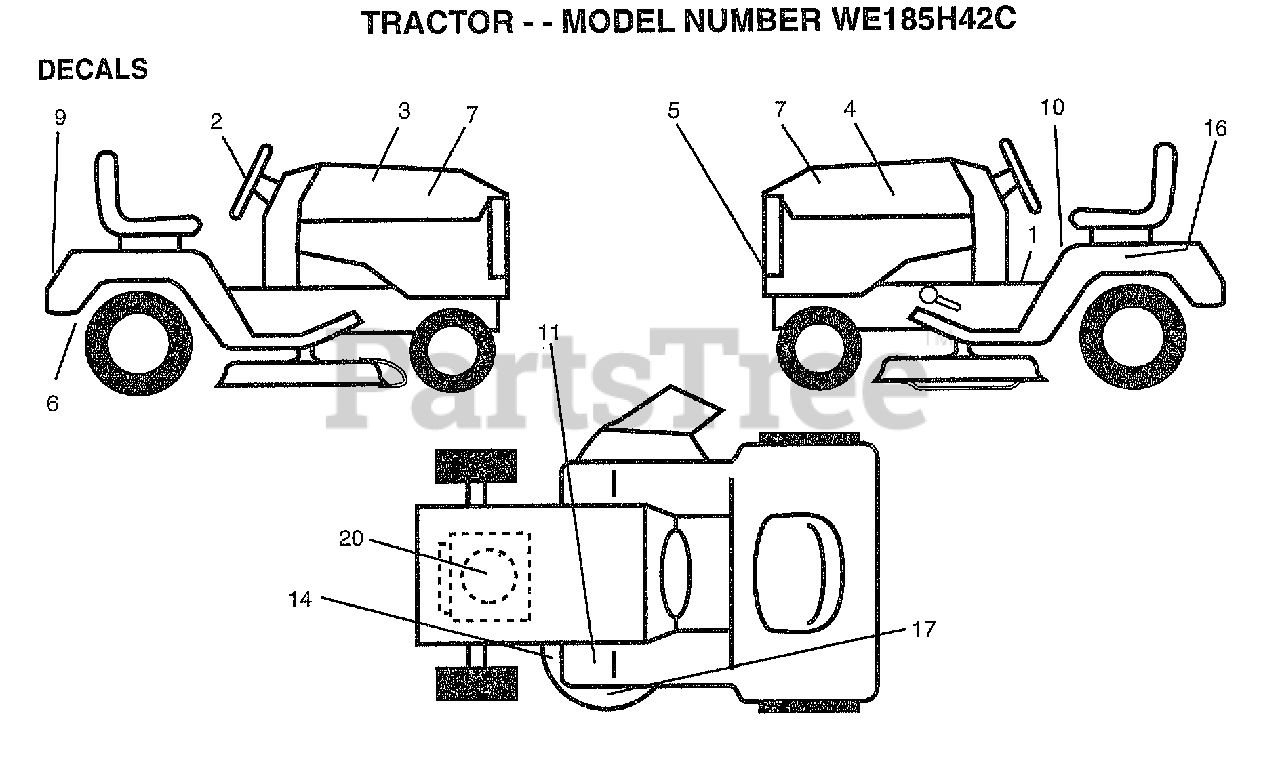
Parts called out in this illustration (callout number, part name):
1	"DECAL INST,SADDLE"
2	"DECAL INS,STRG WH"
3	"DECAL HOOD,RH"
4	DECAL HOOD LH
5	"DECAL GRILLE,LENS"
6	DECAL DRAWBAR LH
7	DECAL PANEL SIDE
9	DECAL-FENDER
10	"DECAL DANGER,FEND"
14	"DECAL-SCHEM,BELT"
16	DECAL.BATRY.3-3908
20	DECAL, HP, ENGINE
